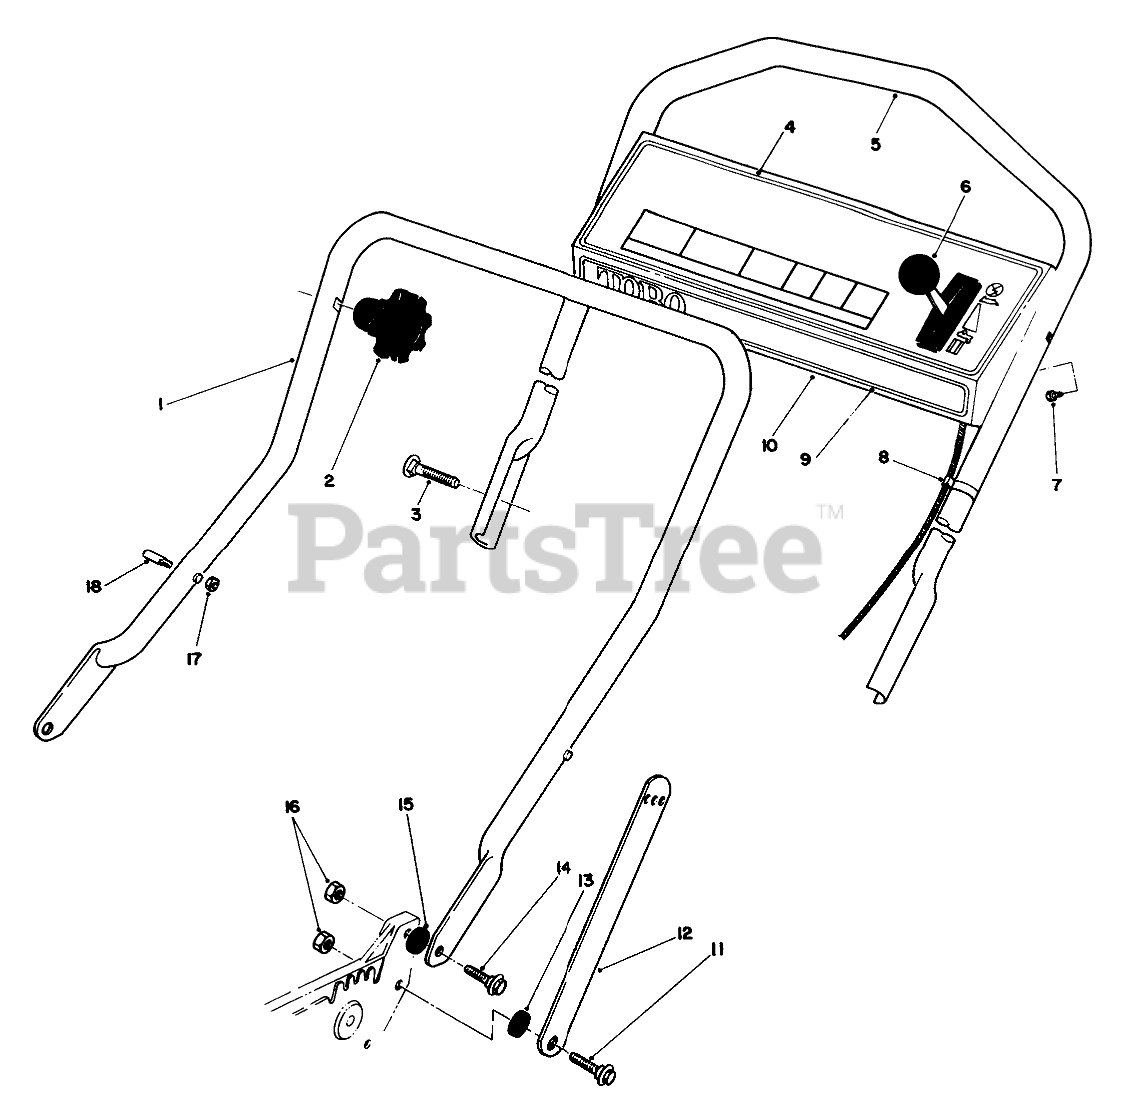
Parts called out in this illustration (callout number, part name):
1	LOWER HANDLE ASM
3	5/16-18 X 2 HNDLE SCREW
4	Decal-Instruction
5	Handle-Upper
6	THROTTLE CONT-SERVICE
7	SCREW-HWHTF
9	Decal-Toro
10	PANEL W/DECAL
11	SCREW-SHOULDER
12	Handle Latch
13	SPACER
14	SCREW-SHOULDER
15	SPACER
16	NUT-LOCK, NI
17	NUT-LOCK, NI
18	HANDLE PIN
